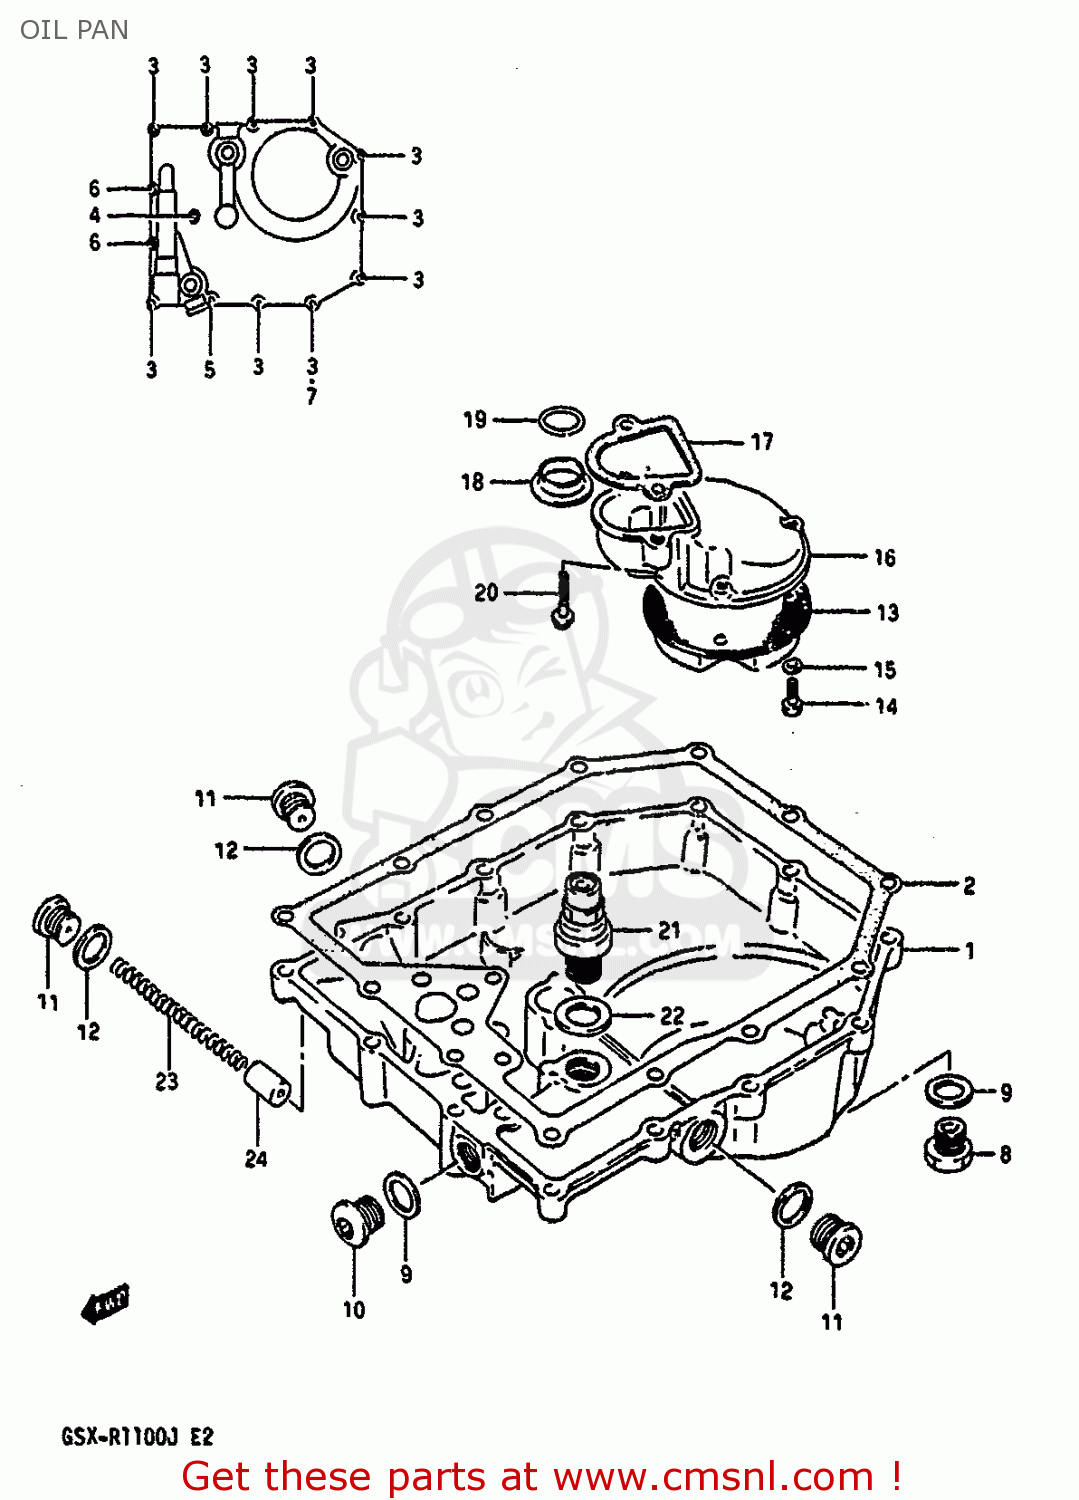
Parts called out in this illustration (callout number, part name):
1	PAN,OIL
2	GASKET,OIL PAN (NAS)
3	BOLT
4	BOLT
5	BOLT
6	BOLT
7	GASKET(5.8X11X1.2) (NAS)
8	PLUG
9	GASKET(14X19.2X2) (NAS)
10	PLUG
11	PLUG
12	GASKET(16X22X2) (NAS)
13	STRAINER,ENGINE OIL
14	BOLT
15	WASHER,LOCK
16	PROTECTOR,OIL STRAINER
17	GASKET,OIL STRAINER PROTECTOR (NAS)
18	GASKET,OIL OUTLET (NAS)
19	O RING(D:3.2,ID:17.8)
20	BOLT
21	VALVE ASSY,OIL RELIEF
22	GASKET(16X22X2) (NAS)
23	SPRING
24	PLUNGER,OIL CONTROLL
